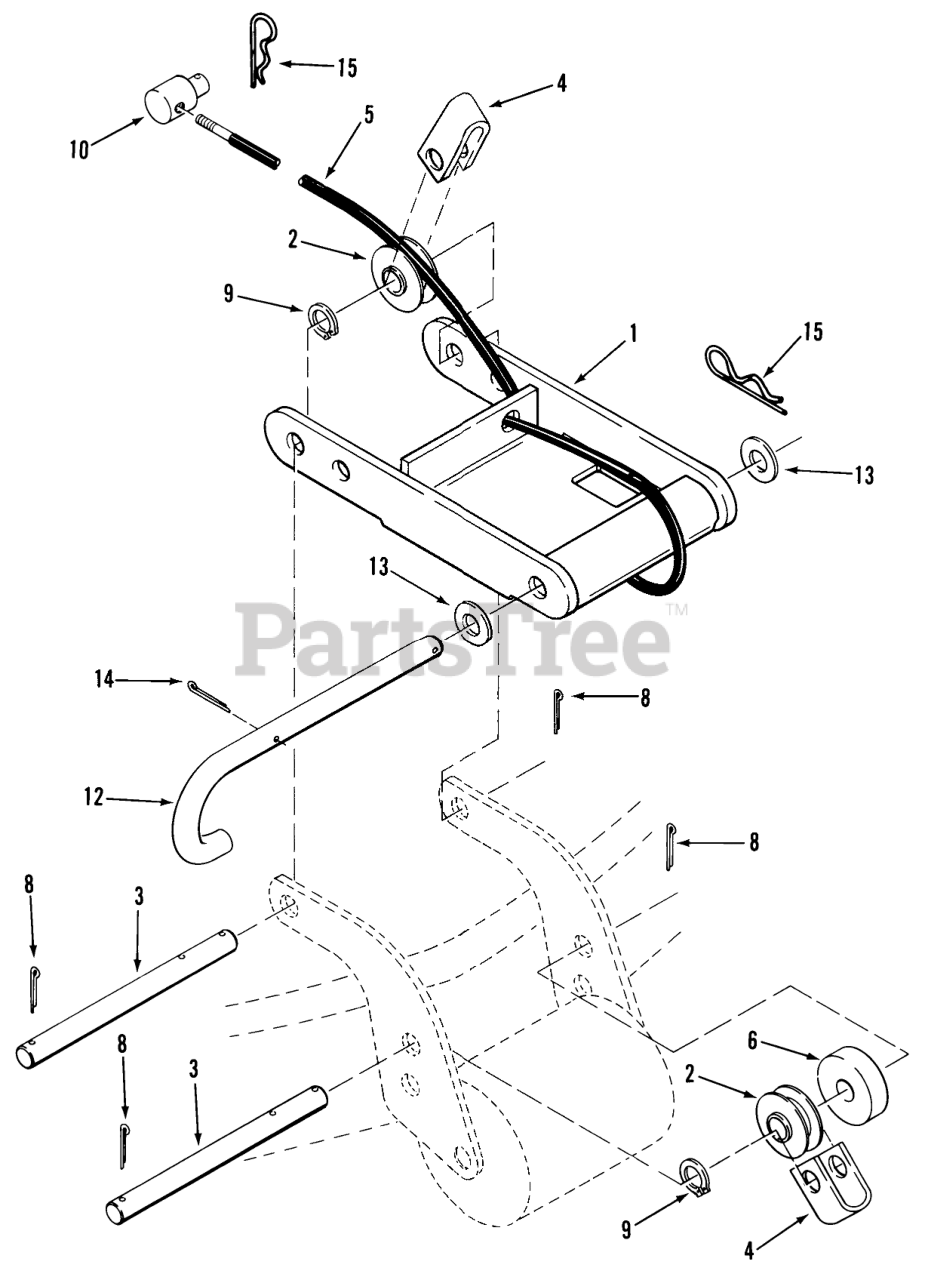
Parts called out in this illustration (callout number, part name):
1	Front Mount
1	Spindle Assembly (Includes Items 2 Thru 8)
2	ROLLER-CABLE
3	Rod
4	STRAP-CABLE
5	ASSY-CABLE
6	SPACER
8	Pop Rivet
9	GRIP RING
10	TRUNNION-CLUTCH ROD
12	"J" Pin
13	Washer
15	Hairpin Cotter
